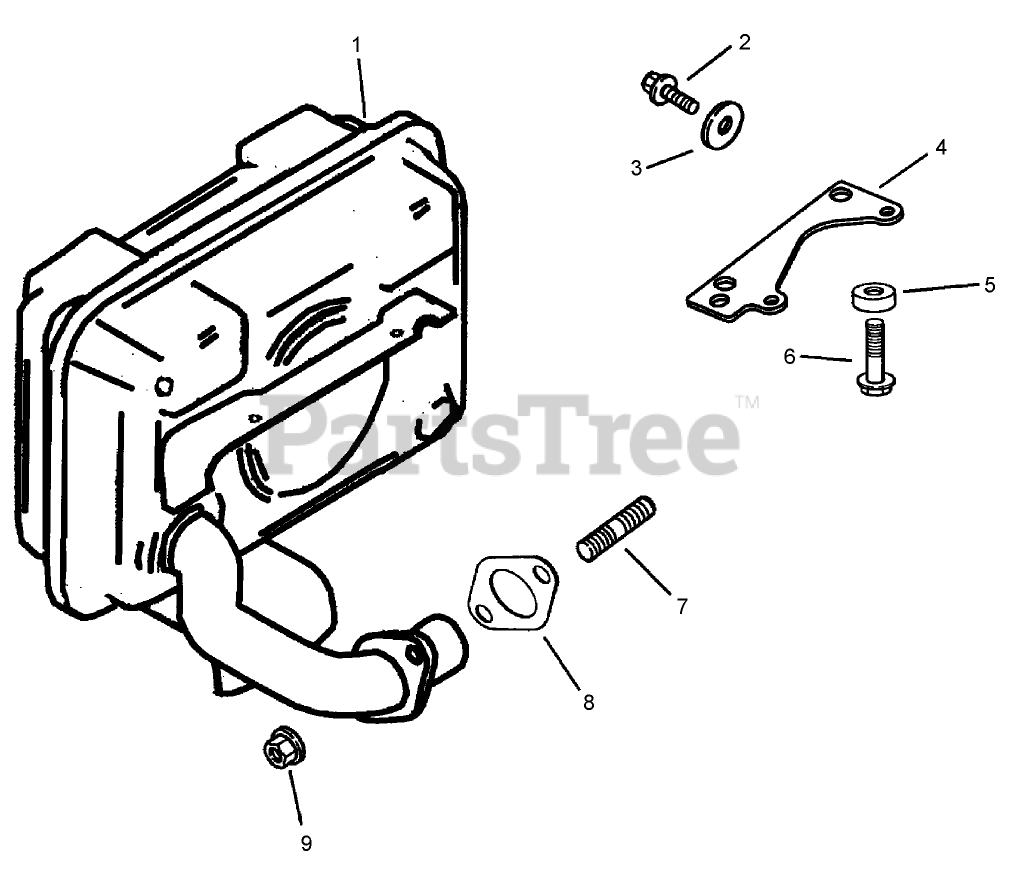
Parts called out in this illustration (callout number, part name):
1	Muffler
2	SCREW-FLANGE, THREAD FORMING (M6X1.0X16)
3	Washer-Plain (1/4in)
4	Bracket-Muffler
5	Spacer
6	SCREW-FLANGE, THREAD FORMING (M6X1.0X25)
7	STUD (M8X1.25X33)
8	Gasket-Manifold, Exhaust
9	NUT-FLANGE (M8X1.25)
